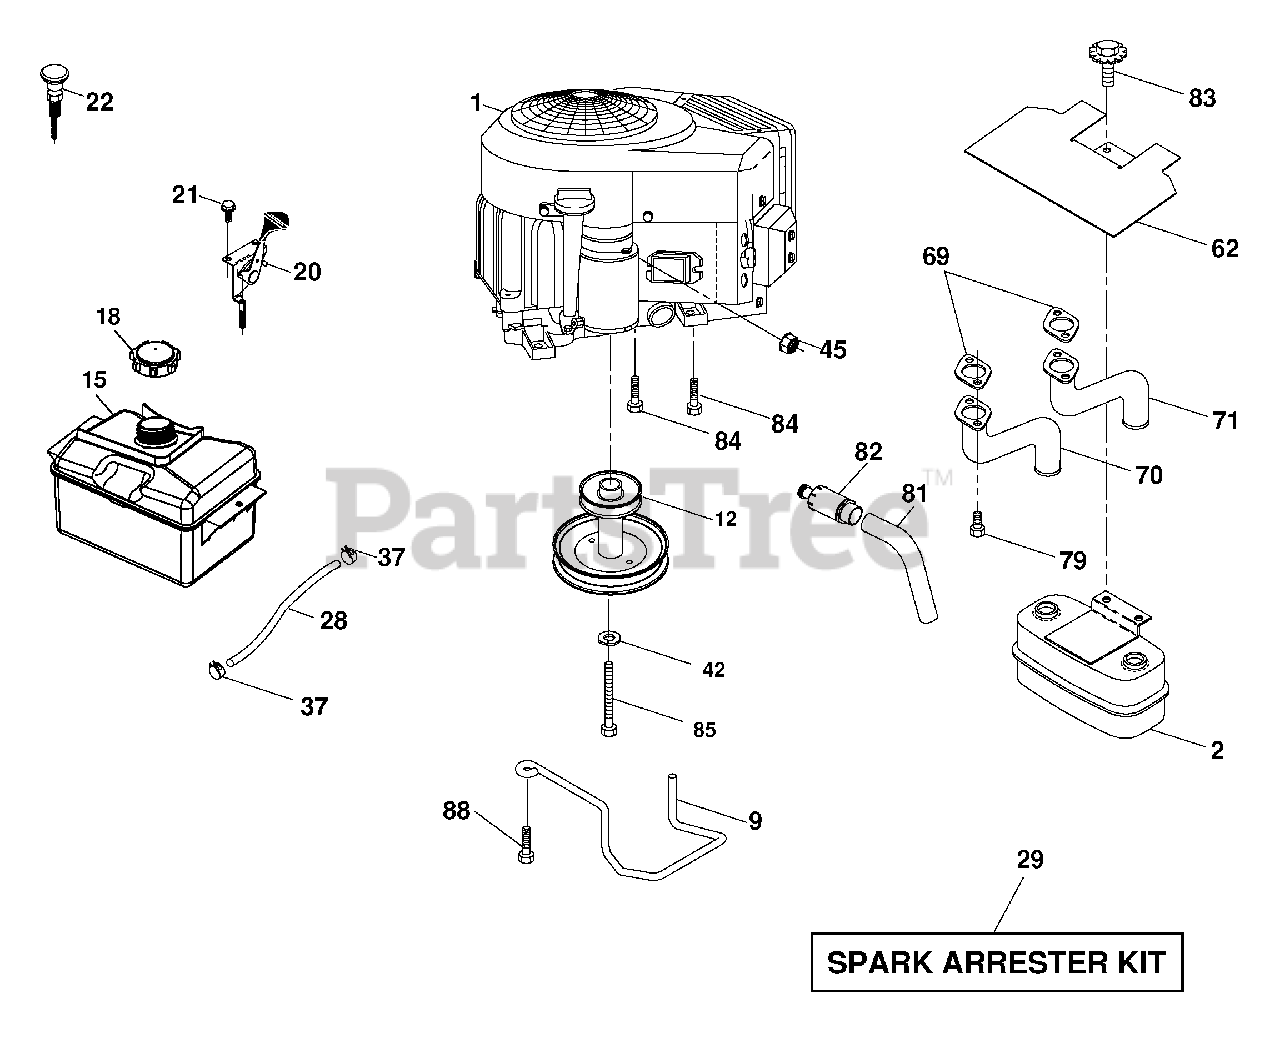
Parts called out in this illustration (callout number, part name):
2	Muffler
9	Keeper Belt Engine
12	Pulley Engine
15	Tank Fuel
18	Cap Asm
20	Control Throttle
21	Screw 10 x 3/4 Single Lead-Hex
22	Control Choke
28	Fuel Line
29	Spark Arrester Kit
37	Clamp Hose
42	Washer Lock 7/16
45	Nut Keps Hex 1/4-20 unc
62	Shield Heat Muffler
69	Gasket
70	Exhaust Tube LH
71	Exhaust Tube RH
79	Screw Socket Head 5/16-18 x 1
81	Tube Drain Oil Easy
82	Plug Drain Oil
83	Bolt 5/16-18 unc x 3/4 w/sems
84	Screw 3/8-16 x 1-1/4
85	Bolt Hex 7/16-20 x 4 x Gr. 5-1.5 Thr.
90	Screw 3/8-16 x 1
